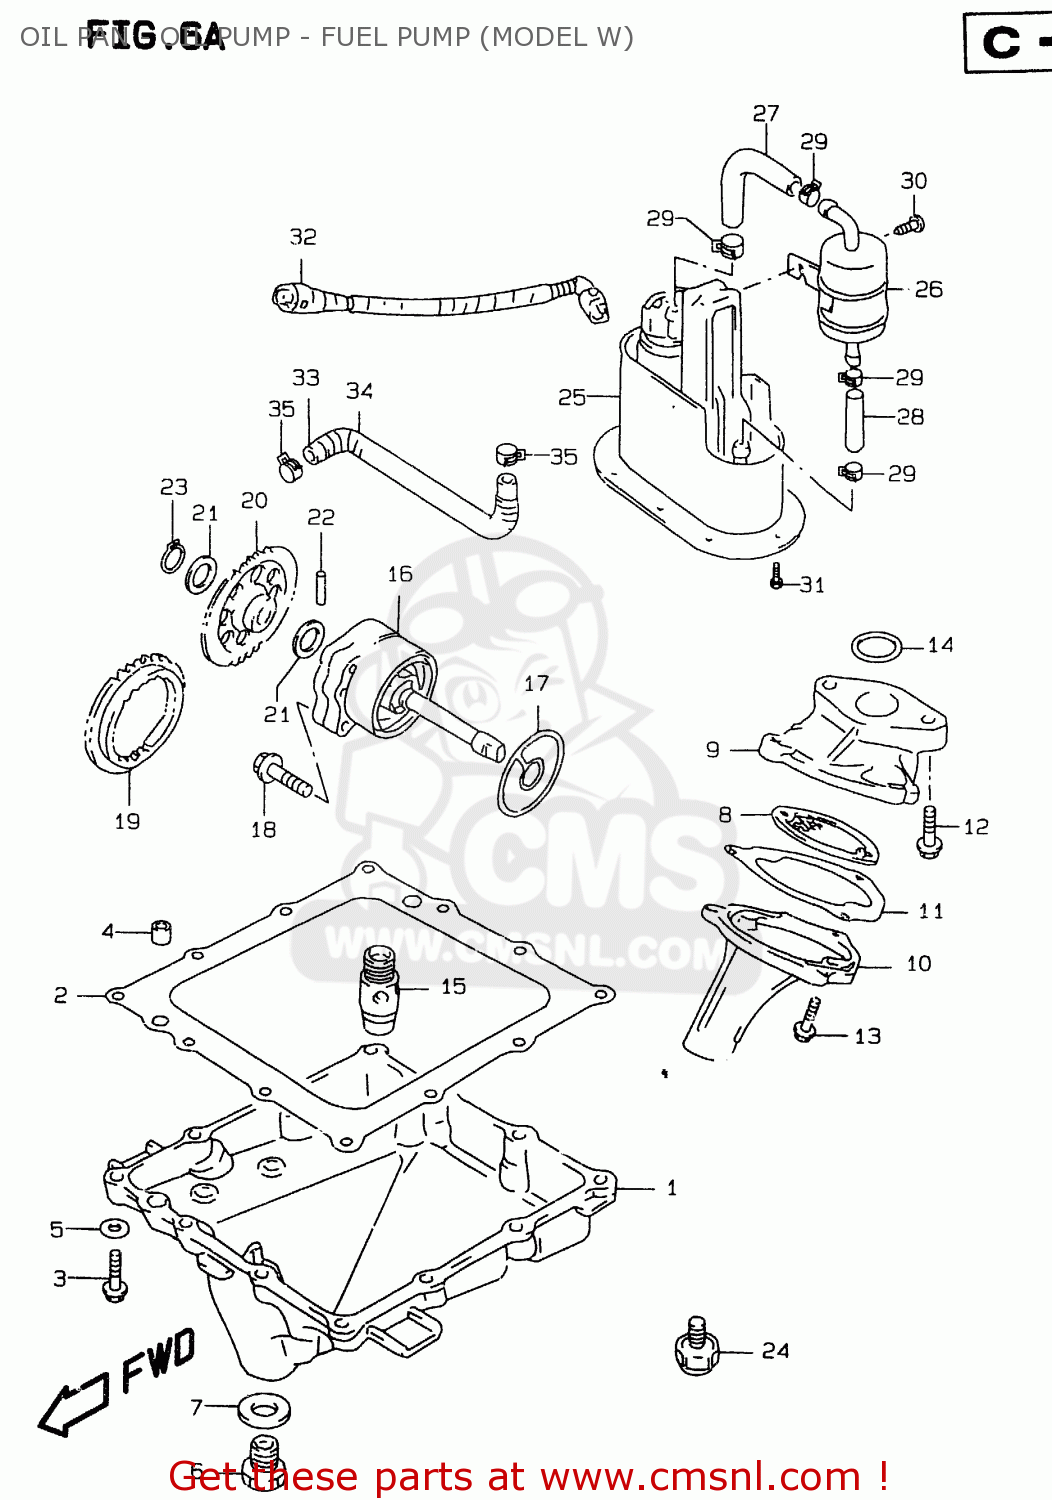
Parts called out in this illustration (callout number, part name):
1	PAN,OIL
2	GASKET,OIL PAN (NAS)
3	BOLT,G/S SWITC
4	PIN
5	GASKET(5.8X11X1.2) (NAS)
6	PLUG
7	GASKET(13.8X18.8X4.8) (NAS)
8	STRAINER,ENGINE OIL
9	PROTECTOR,OIL STRAINER
10	COVER,OIL STRAINER
11	GASKET,OIL STRAINER
12	BOLT
13	BOLT
14	O RING(D:2.62,ID:20.3)
15	VALVE ASSY,OIL RELIEF
16	PUMP ASSY,ENGINE OIL
17	O RING,OIL PUMP
18	BOLT
19	GEAR,OIL PUMP DRIVE (NT
20	GEAR,OIL PUMP DRIVEN
21	SHIM(12X20X0.5)
22	PIN(5X18)
23	CIRCLIP,12 MM
24	SWITCH ASSEMBLY,OIL PRESSURE
25	PUMP ASSEMBLY,FUEL
26	FILTER,FUEL
27	HOSE,FUEL
28	HOSE(7.6X14X600)
29	CLIP
30	SCREW
31	BOLT
32	HOSE,FUEL
33	HOSE(5.4X11.4X600)
34	(CA) SPRING
35	CLIP
